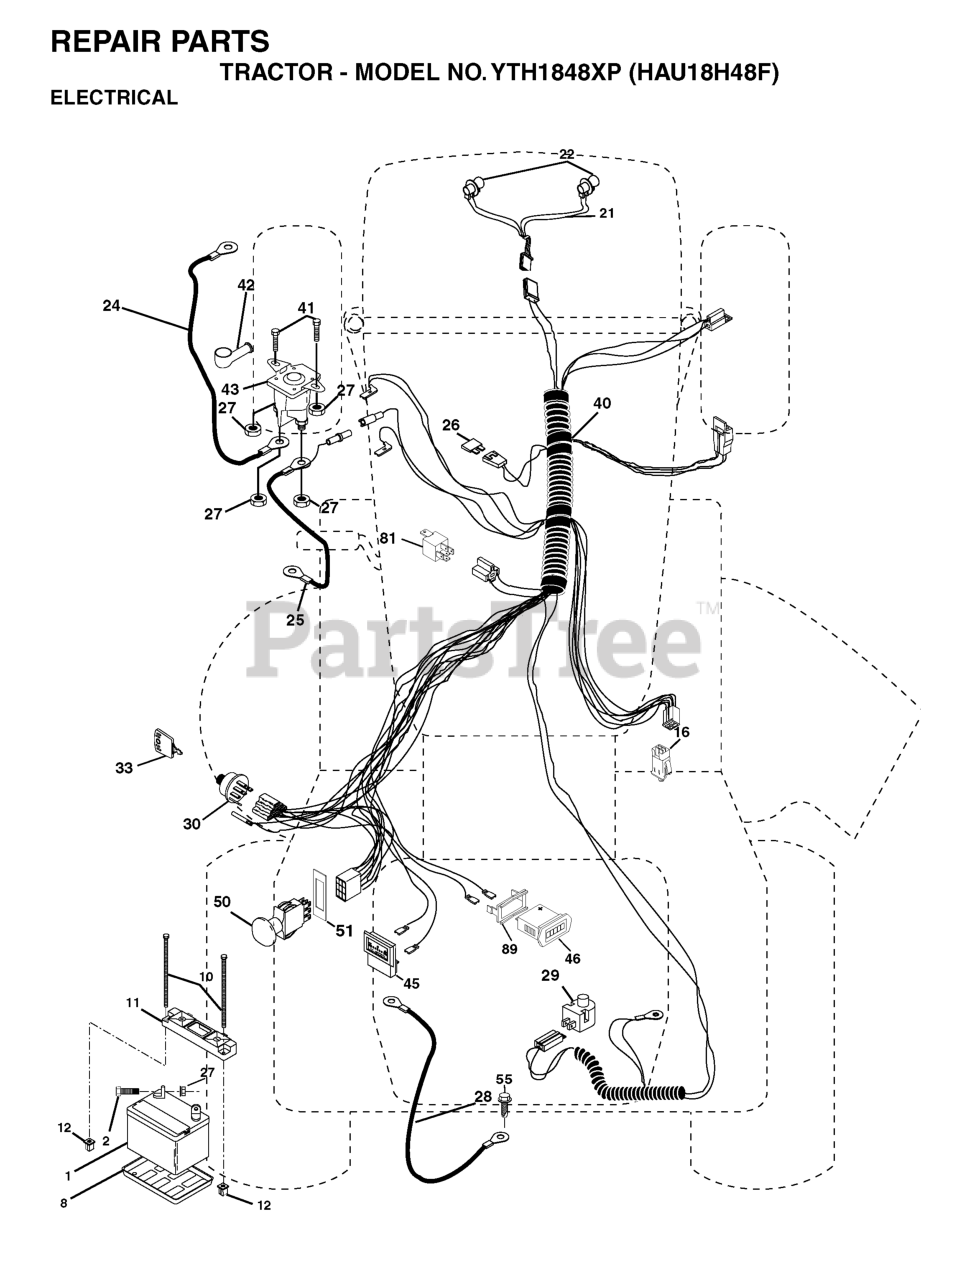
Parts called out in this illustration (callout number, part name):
1	BATTERY 12V .35 AMP
2	BOLT.HEX.1/4.X.3/4.DICHROMATE
8	BATTERY TRAY T
10	BOLT 1/4-20 X 7.5
11	BATTERY HOLDDOWN FRONT MOUNT
12	NUT, PUSH NYLON 1/4" BATTERY
16	SWITCH INTERLOOK PUSH-IN
21	HARNESS.ASM.LIGHT WSL
24	BATTERY CABLE GT
25	CABLE BATTERY 6 GA 22" W/16W
26	FUSE 20AMP
27	NUT
28	CABLE GROUND 6 GA 21" 90T BLK
29	PLUNGER SWITCH (COLOR:OLIVE)
30	IGNITION SWITCH
33	KEY MLD GEN DELTA
40	HARNESS IGN.
41	BOLT
42	TERMINAL COVER
43	SOLENOID
46	HOUR METER
50	RP.PTO.SWITCH.8 TERMINAL.BLACK
51	FRAME RETAINING RING
55	Screw 5/16-18 x 1/2 Hex, Self Tapping 5/16-18 x 1/2
81	RELAY.ASSY.T
89	BRACKET SNAP-IN HOURMETER
